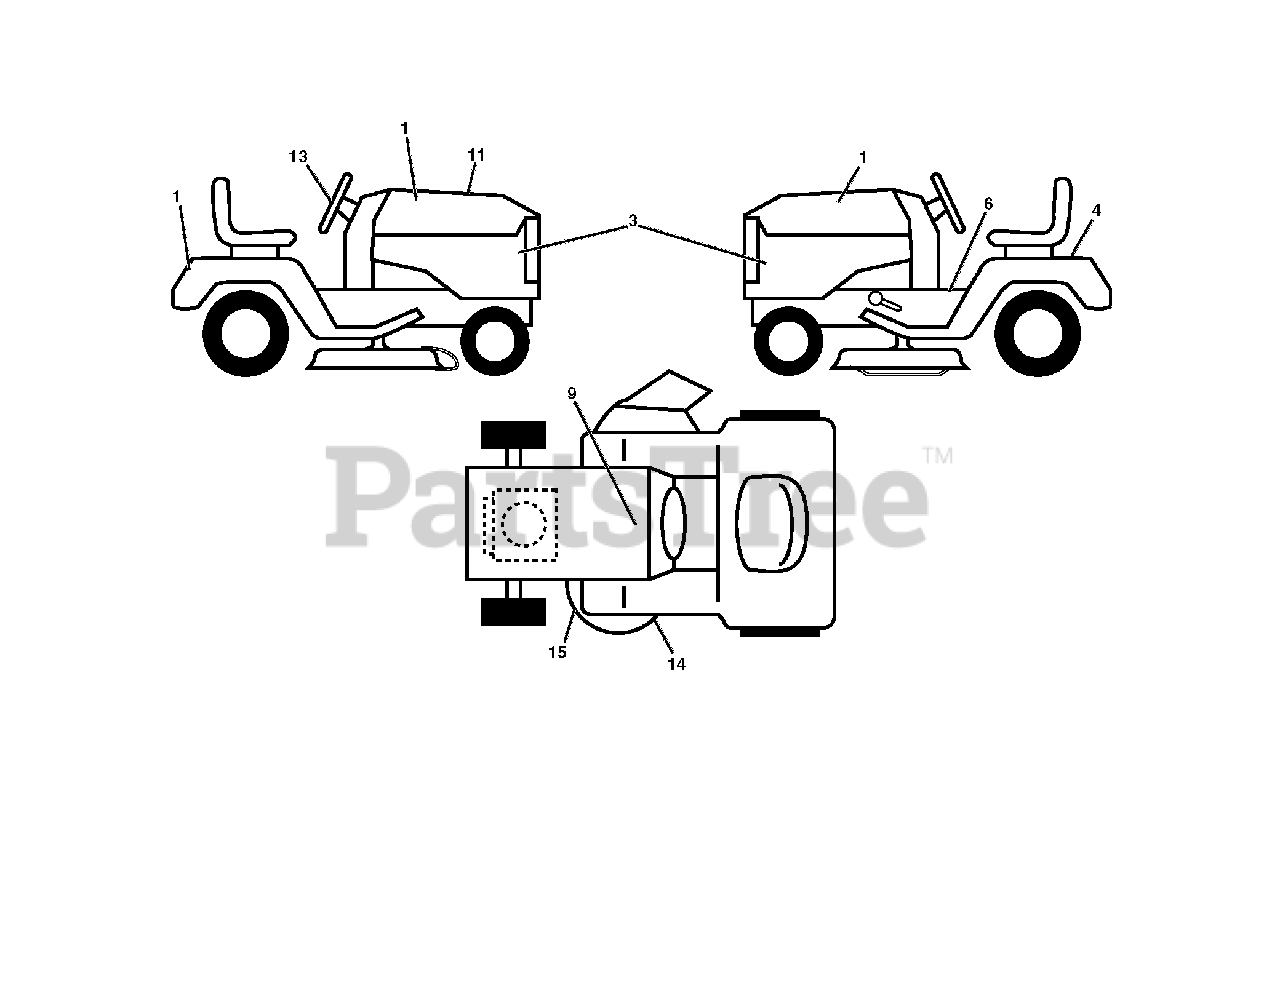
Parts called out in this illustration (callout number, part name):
1	DECAL, DIXON LOGO, DOMED
4	DECAL SERVICE
6	DECAL.WARN.START.INSTRUCTIONS
9	DECAL BTRY SYMBOLS
11	DECAL.RPL
13	DECAL.WHEEL.STEER.DIXON
14	DECAL.MOWER.SCH.48/54
15	DECAL.MOWER
